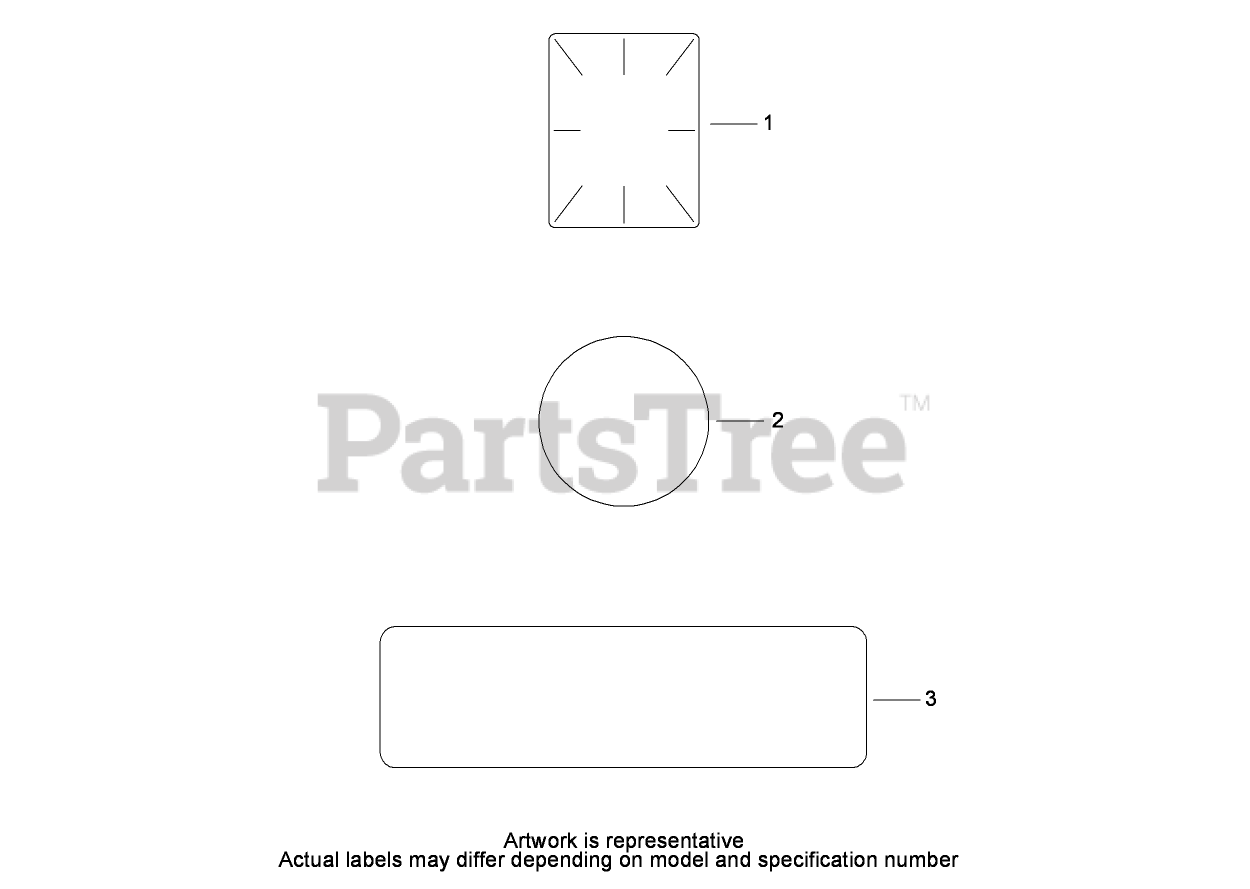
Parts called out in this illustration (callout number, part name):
1	DECAL-LAMINATE, CLEAR
2	Decal-Screen, Grass
3	Decal-20 HP
